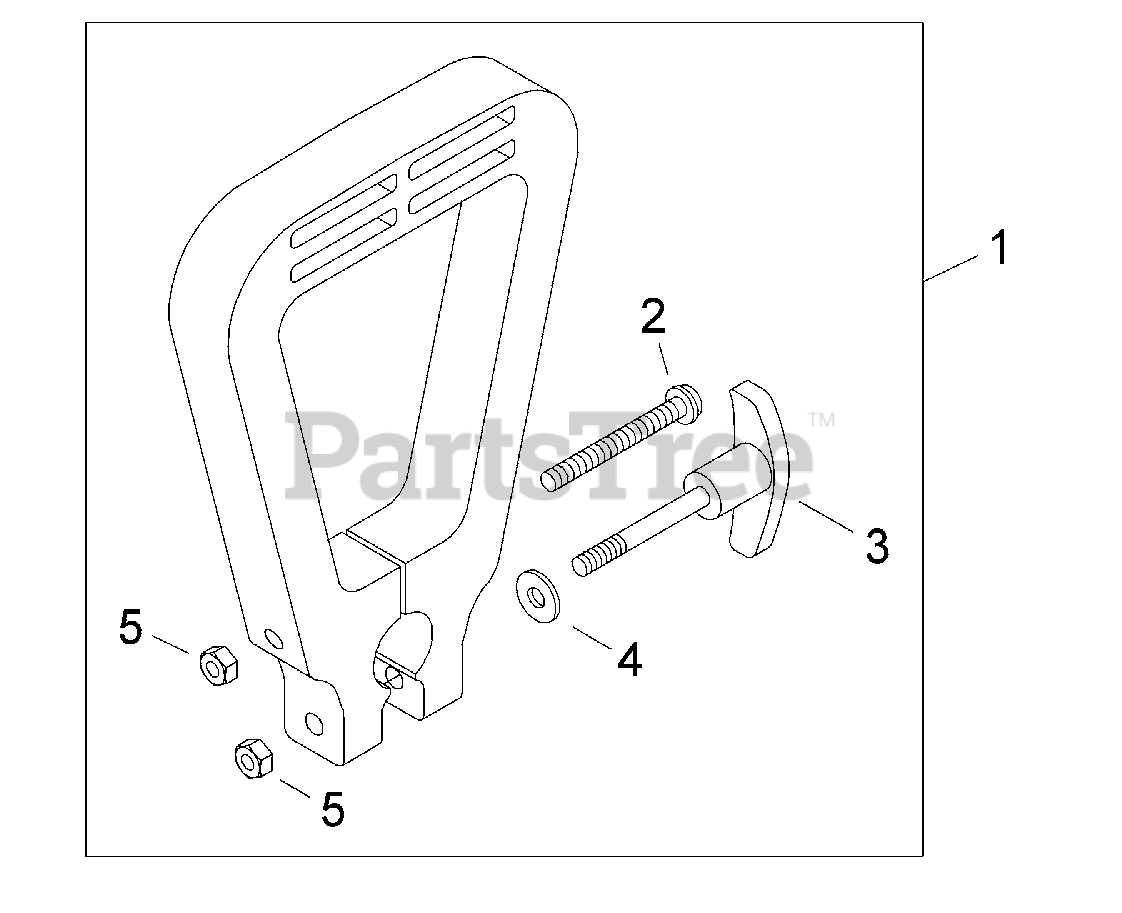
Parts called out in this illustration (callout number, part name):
1	HANDLE ASSY
2	SCREW
3	THUMBSCREW
4	WASHER
5	NUT - 6
